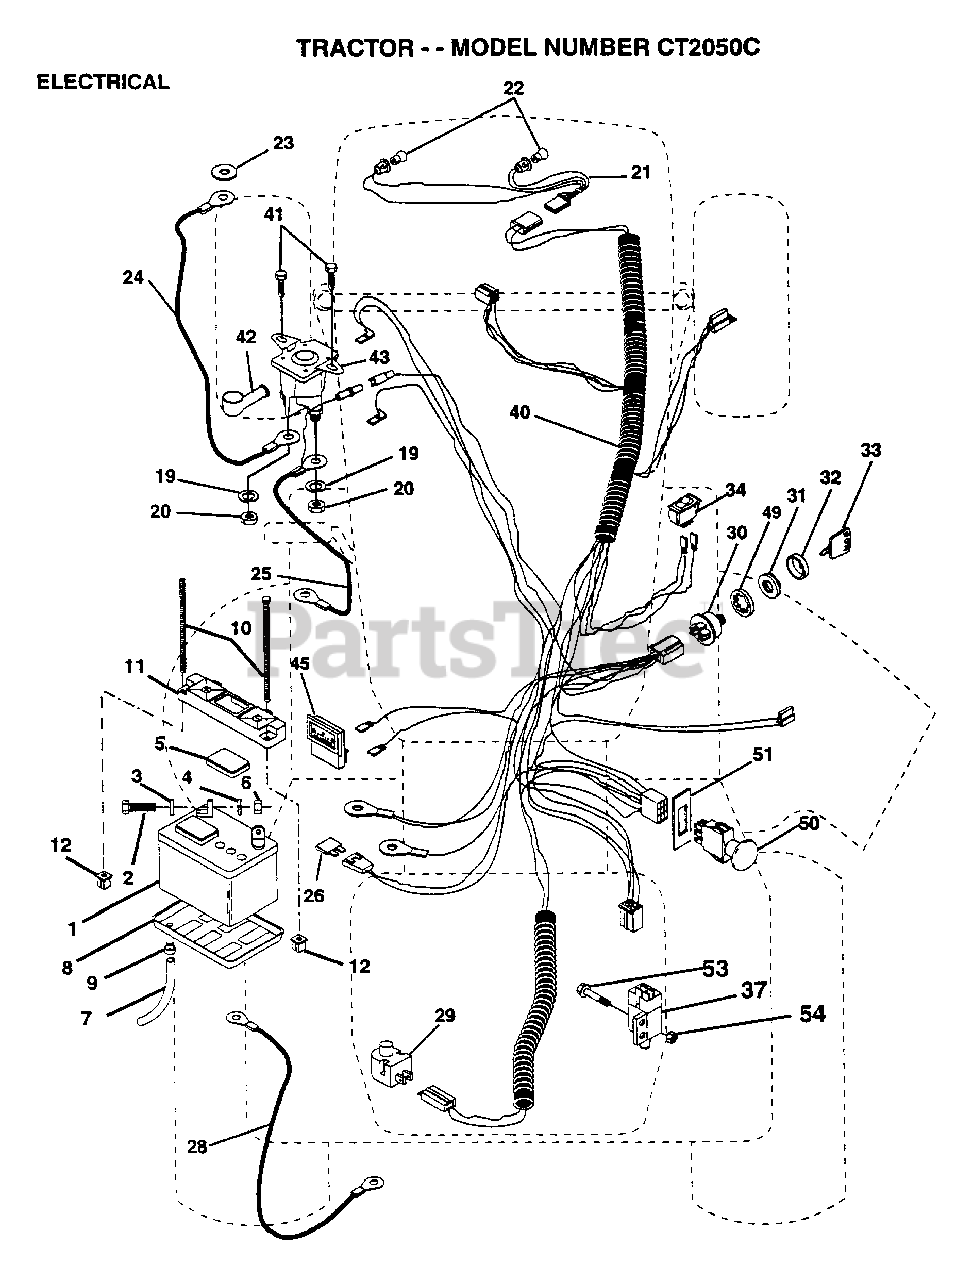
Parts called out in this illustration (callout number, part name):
2	BOLT LT
3	WASHER
4	LOCKWASHER
5	"CAP,BATTERY "
7	"DRAIN TU T, BATT"
8	"TRAY T, BATTERY"
9	HOSE CLAMP T
20	NUT
21	"HARNESS,LIGHT SOC"
22	HEADLAMP BULB
23	LOCKWASHER
24	"CABLE T, BATTERY"
25	CABLE.6GA.12.5.
26	FUSE HYT
28	CABLE T
29	SWITCH SEAT
32	COVER KEY SWITCH
33	KEY MLD GEN DELTA
34	SWITCH LT
37	SWITCH INTERLOCKT
40	HARNESS.IGN.SRSGT
41	SCREW
45	AMMETER
49	LOCKWASHER
51	RING RETAIN PTO
53	SCREW
54	"NUT,KEPS"
